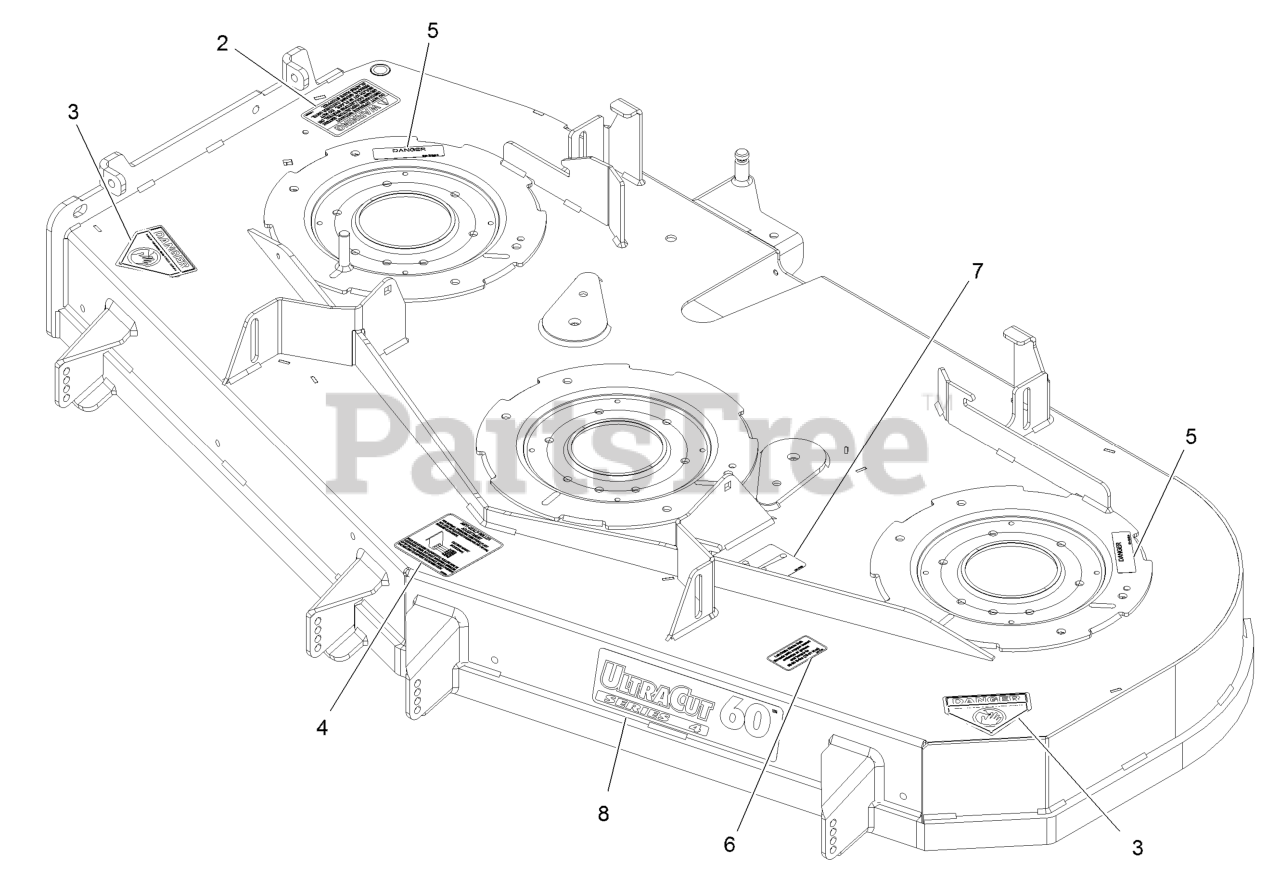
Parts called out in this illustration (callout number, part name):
2	DECAL-WARNING, DISCHARGE
3	DECAL-DANGER
4	DECAL,ANTISCALP
5	DECAL-COVER, MISSING
6	DECAL,BOLT TORQUE
7	DECAL-ROUTING, BELT
8	DECAL,ULTRACUT 60 SERIES
